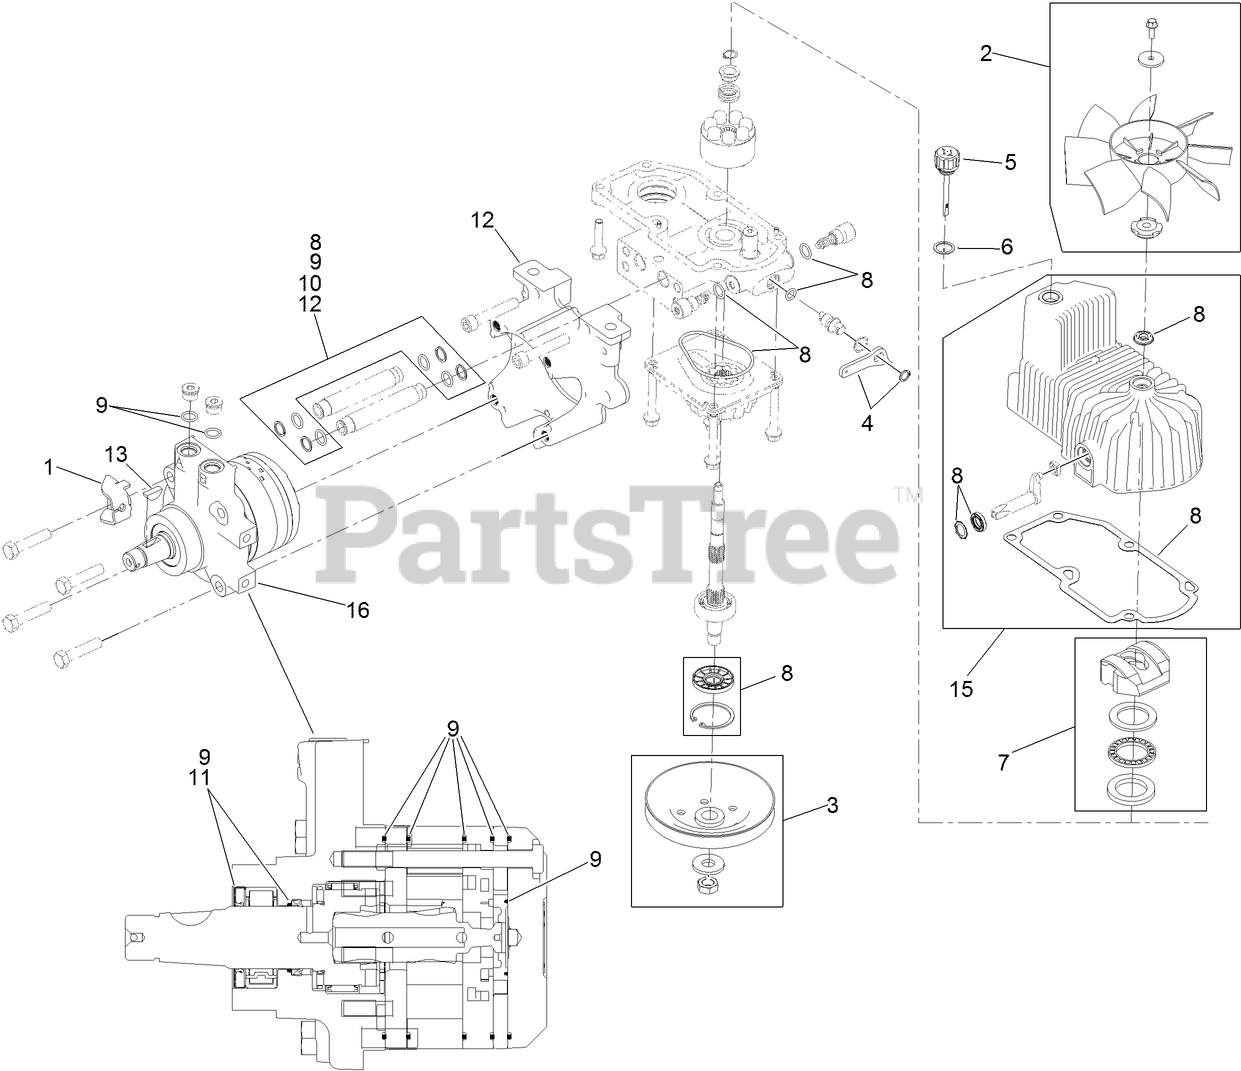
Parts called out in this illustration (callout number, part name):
1	BRACKET-ANCHOR, CABLE
2	FAN KIT
3	PULLEY KIT
4	HANDLE-BYPASS VALVE, HYDRO
5	DIPSTICK-HYDRO W/GASKET
6	GASKET-DIPSTICK, HYDRO
7	SWASH BLOCK KIT
8	PUMP SEAL KIT
9	MOTOR SEAL KIT
10	TUBE SEAL KIT
11	OUTPUT SHAFT SEAL KIT
12	NOSE CUP-UHT
12	CUP-NOSE
13	KEY-WOODRUFF
15	HOUSING-HYDRO, LH
16	MOTOR-HYDRAULIC, LH 280CC
